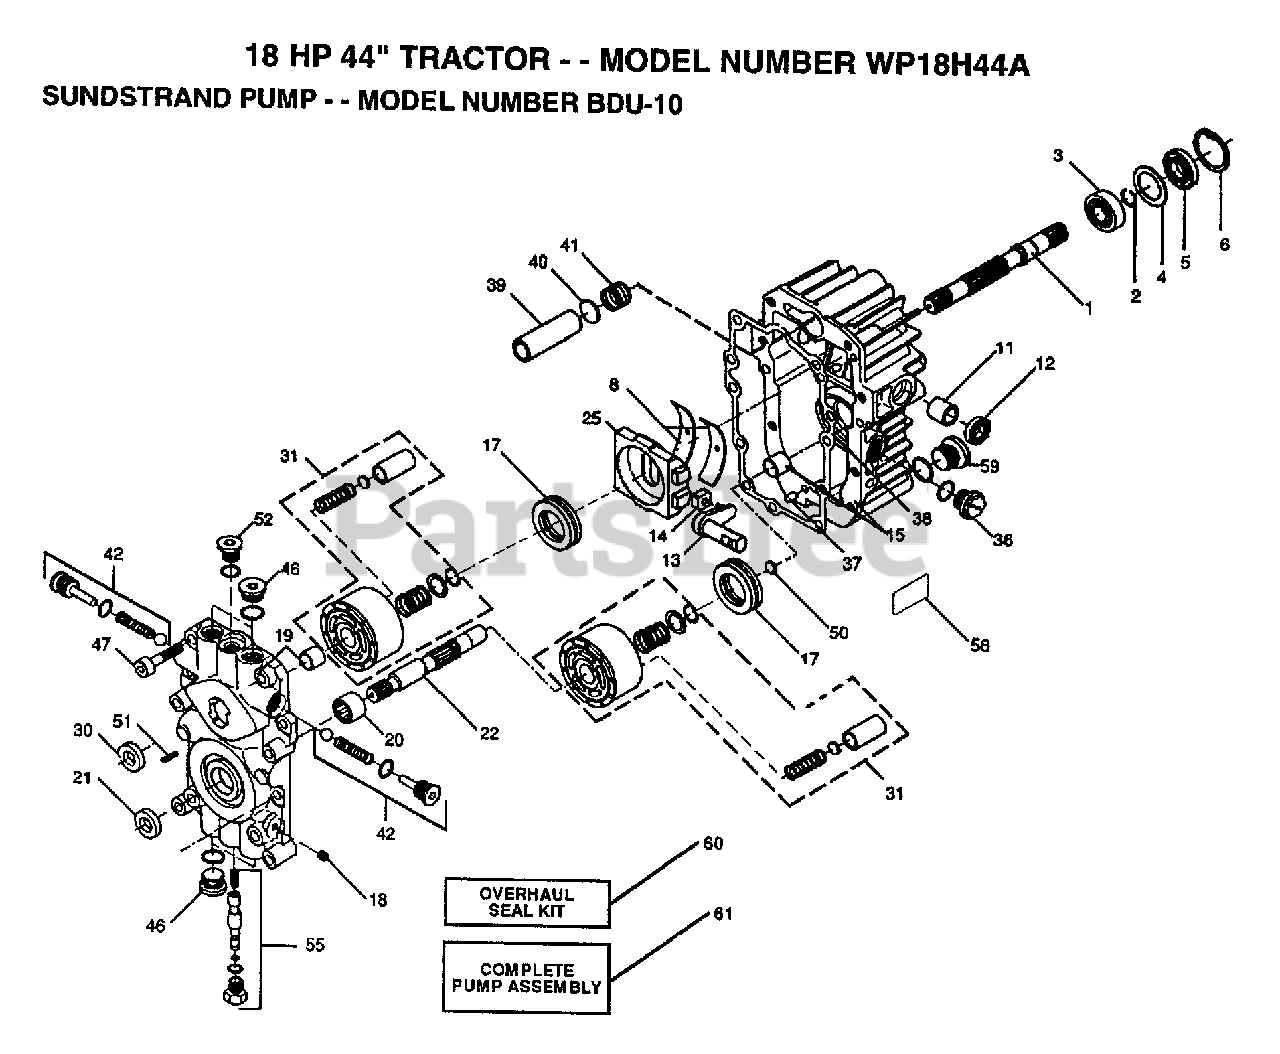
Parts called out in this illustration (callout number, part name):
1	SHAFT.PU.2003022
2	RETAINIANG RING-(2003016)
3	BALL BEARING
4	SPACER
5	SEAL LIP
6	RING.RET.2003052
8	CRADLE BEARING (2003023)
11	BEARING
12	SEAL.9008000-0126
13	TRUNION ARM (2003005)
14	GUIDE.2000015.HYD
18	PLUG PIPE
19	"KIT,CTR SECTION (2513007)"
20	NEEDLE BEARING
21	LIP SEAL-9008000-0127
22	SHAFT
25	"SWASHPLATE,VARIAB"
30	SEAL LIP
31	"KIT,BLOCK CYLINDE"
36	"PLUG,PLASTIC 9005200-8700"
37	PIN
38	GASKET.20030600
39	FILTER
40	WASHER (2000011)
41	SPRING
42	KIT.VALVE.2513014
46	PLUG
47	SCREW9007314-0808
50	WASHER
51	PIN
52	PLUG
55	"KIT,BYPASS VALVE"
58	ADHESIVE LABEL
59	PLUG
60	"KIT,OVERHEAD SEAL -2513013"
61	PUMP.BDU-10S-114
